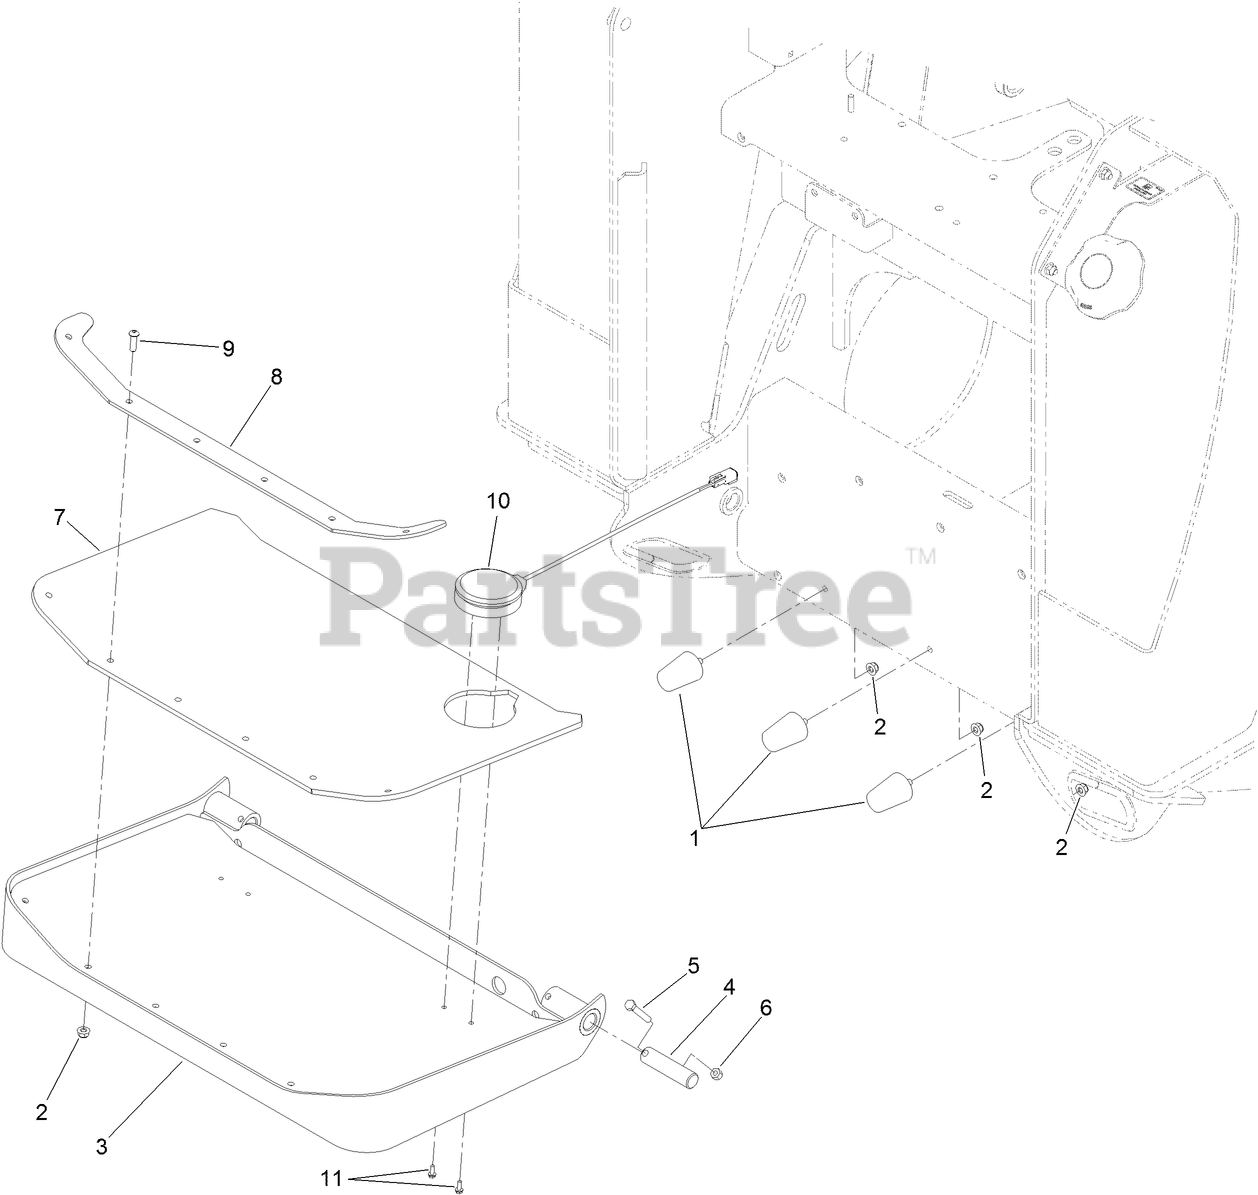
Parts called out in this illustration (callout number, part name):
1	BUMPER
2	NUT-HF, NI
3	PLATFORM
4	PIN-PIVOT
5	SCREW-HH
6	NUT-LOCK, NI
7	PAD-PLATFORM
8	BRACKET-CLAMP, PLATFORM
9	SCREW-HSBH
10	SWITCH-FOOT
11	SCREW-TAPTITE
